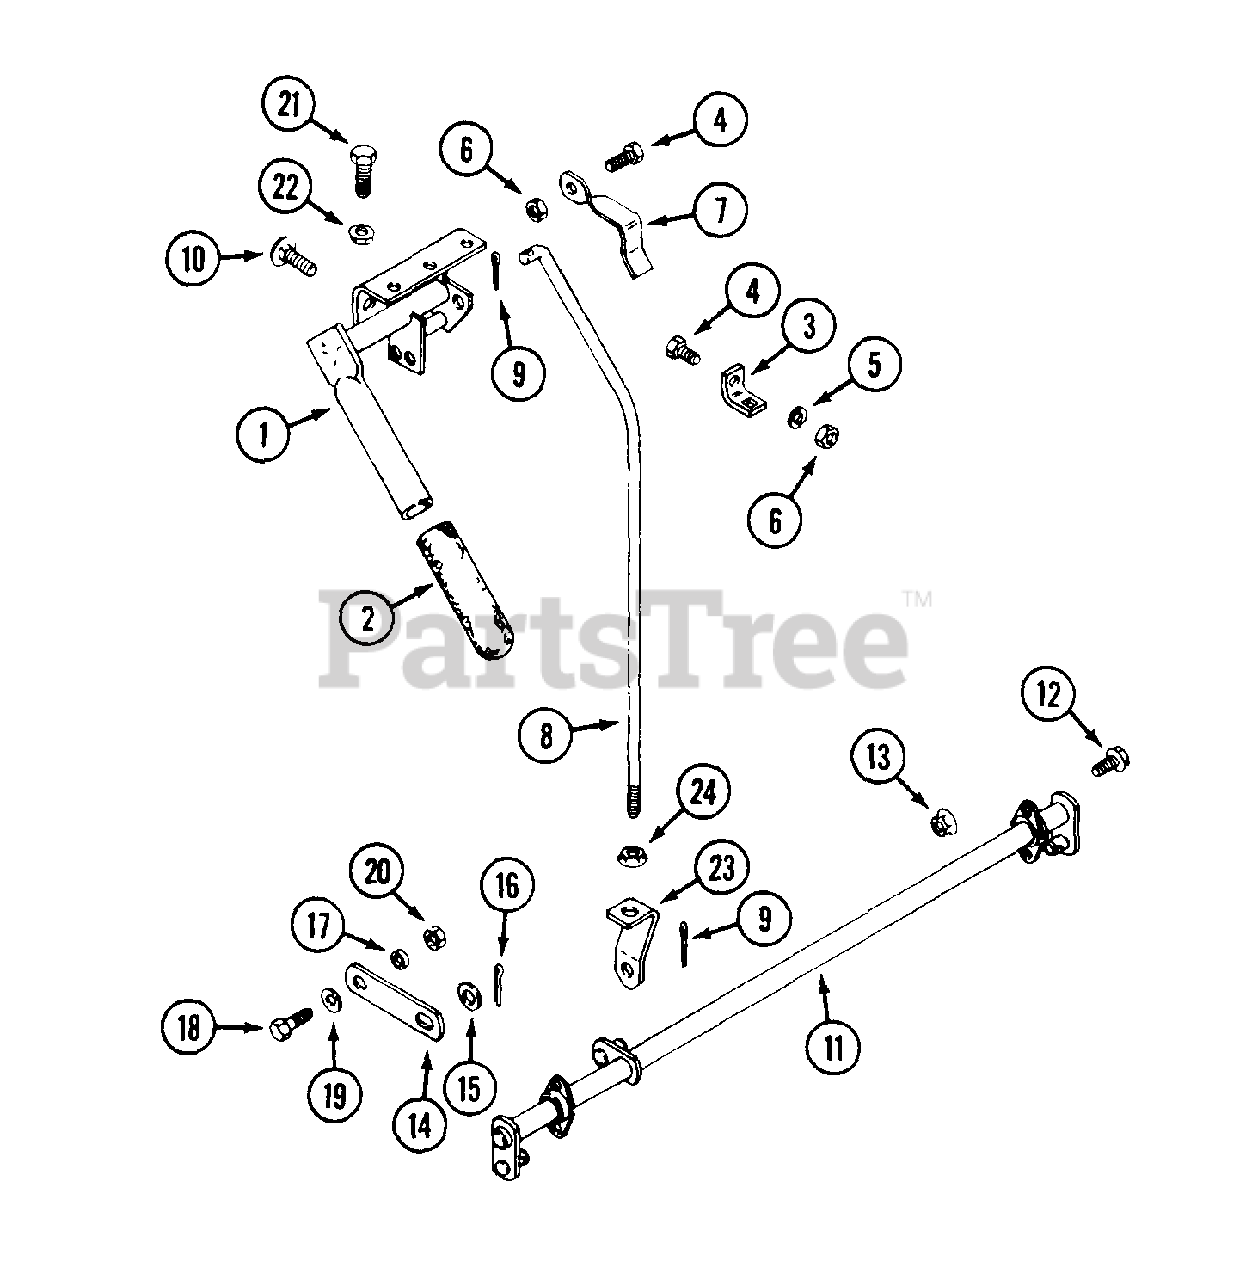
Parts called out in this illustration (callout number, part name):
1	LEVER - brake
2	GRIP - handle
3	STOP - lever
4	BOLT - 1/4" - 20 x 3/4"
5	LOCKWASHER - 1 /4"
6	NUT - 1/4" - 20
7	ARM - actuator
8	ROD - brake
9	PIN - cotter 1/8" x 1"
10	BOLT - 1/4" - 20 x 1" carriage
11	SHAFT - cross
12	BOLT - 1 /4" - 20 x 1/2" flange
13	NUT - 1/4" - 20 flange lock
14	BAR - brake link
15	WASHER - .40" x .81"
16	PIN - cotter 1/8" - 1"
18	BOLT - 1/4" - 20 x 1"
19	WASHER - .31" x .75"
20	NUT - 1/4" - 20 lock
21	BOLT - 5/16" - 18 x 5/8"
22	NUT - 5/16" - 18 flange lock
23	CLEVIS - brake
24	NUT - 3/8" - 18 flange lock
